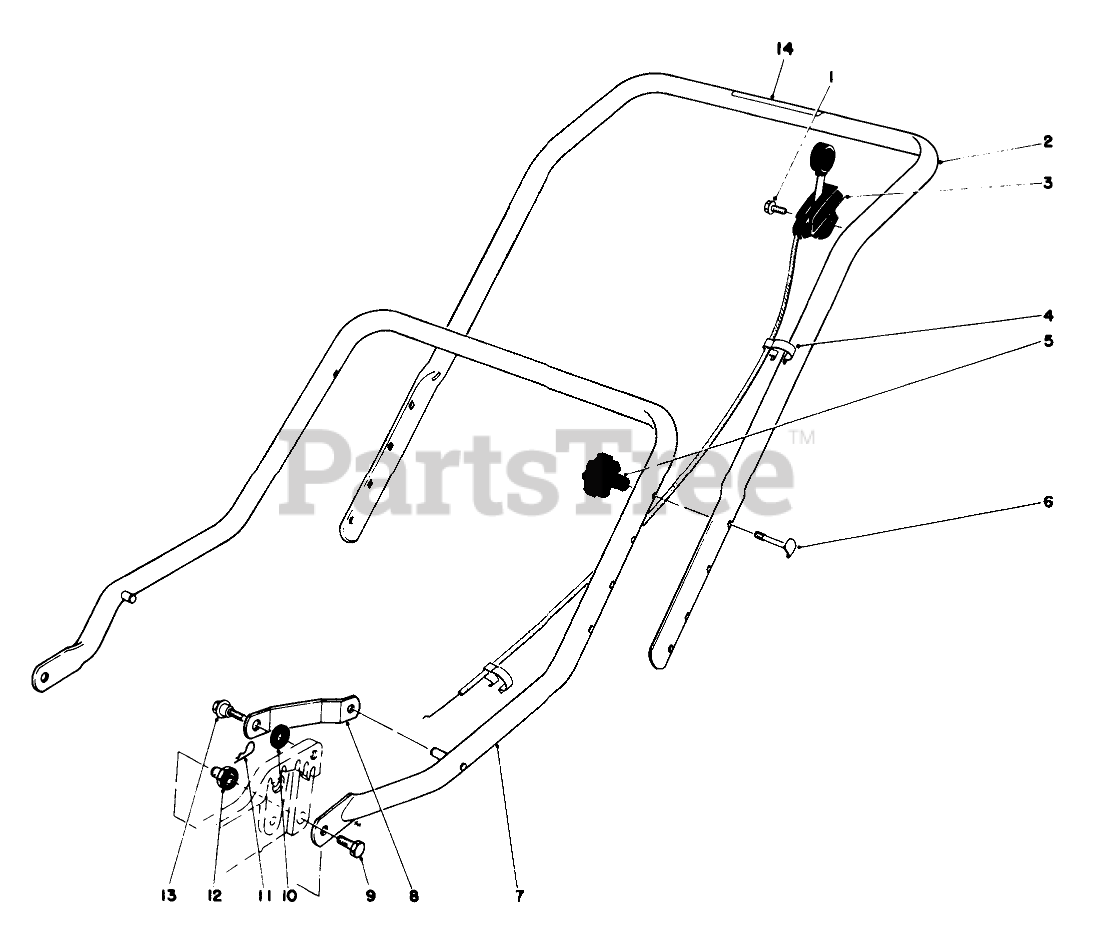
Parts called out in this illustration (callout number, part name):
2	Upper Handle
3	Throttle Control
4	BOWDEN CLIP
6	HANDLE SCREW
7	Lower Handle
8	HANDLE LATCH
9	SCREW-HH
10	SPACER
11	PIN-COTTER, HAIR
12	HANDLE PIVOT NUT
13	SCREW-SHOULDER
14	Decal
